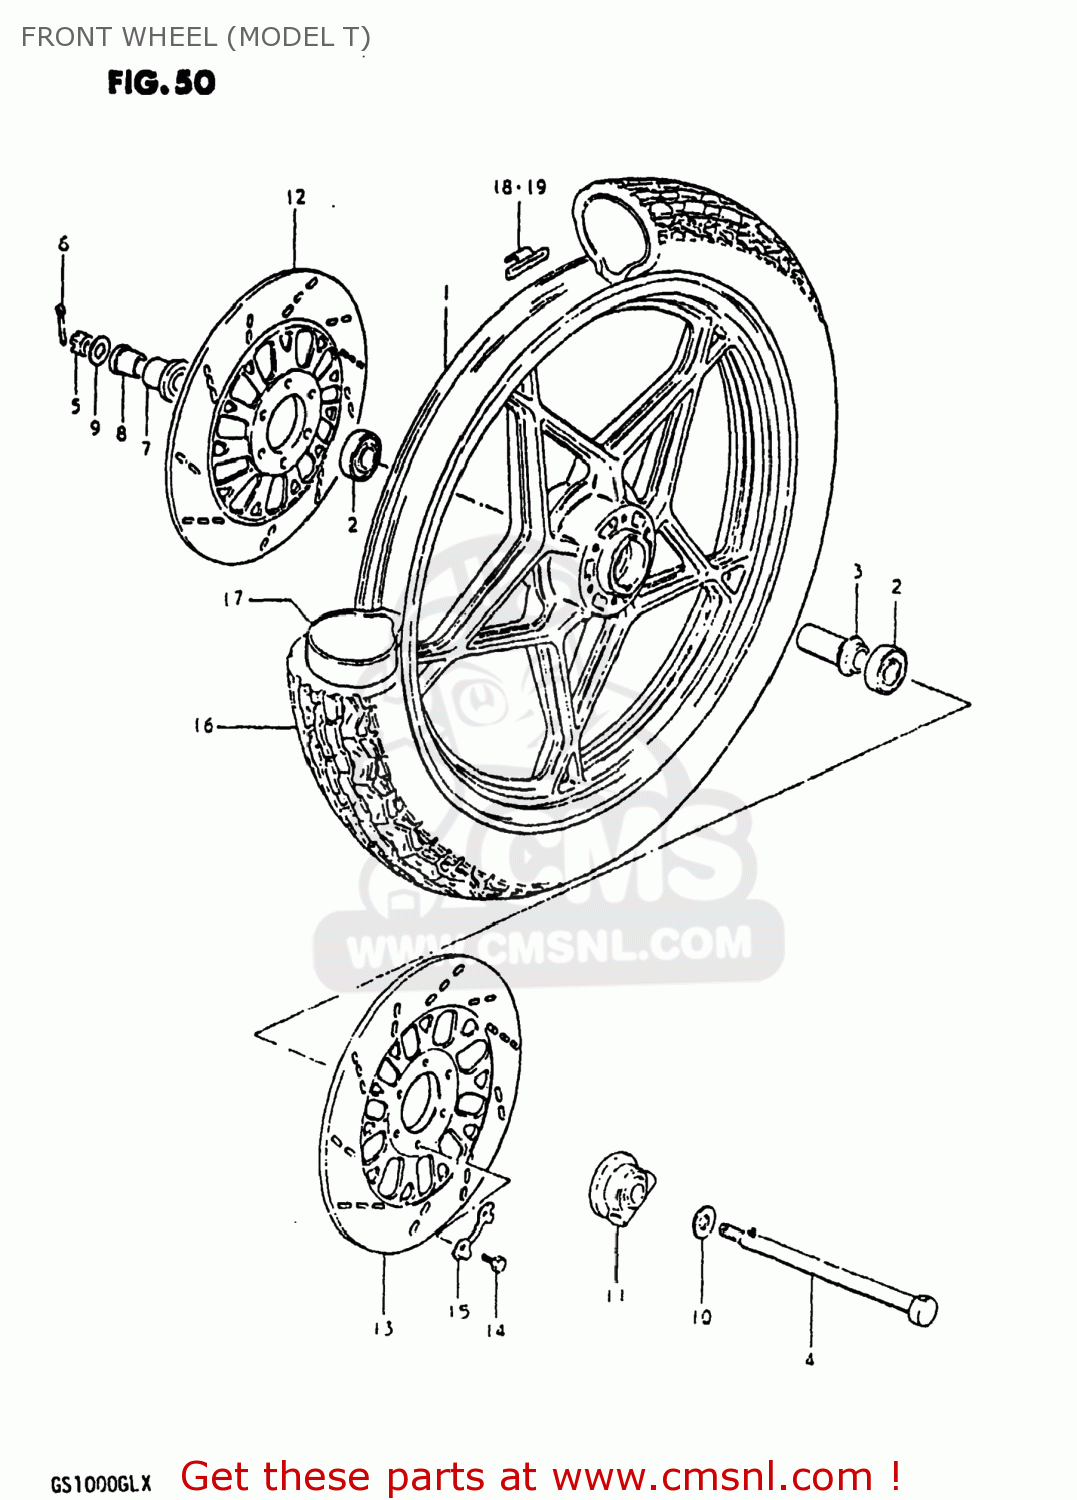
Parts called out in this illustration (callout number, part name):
1	CASTING WHEEL,FRONT 1.85
2	BEARING
3	SPACER,FR HUB BEARING
4	AXLE,FR
5	NUT 12MM
6	COTTER PIN
7	SPACER,FR AXLE,R
8	SPACER
9	WASHER
10	WASHER(15.5X26X2.3)
11	BOX ASSY,SPEEDOMETER GEAR
12	DISC,FR BRAKE,R
13	DISC,FR BRAKE,L
14	BOLT(8X25)
15	WASHER
16	TIRE,FRONT
17	TUBE,INNER
18	BALANCER,WHEEL
19	BALANCER,WHEEL
